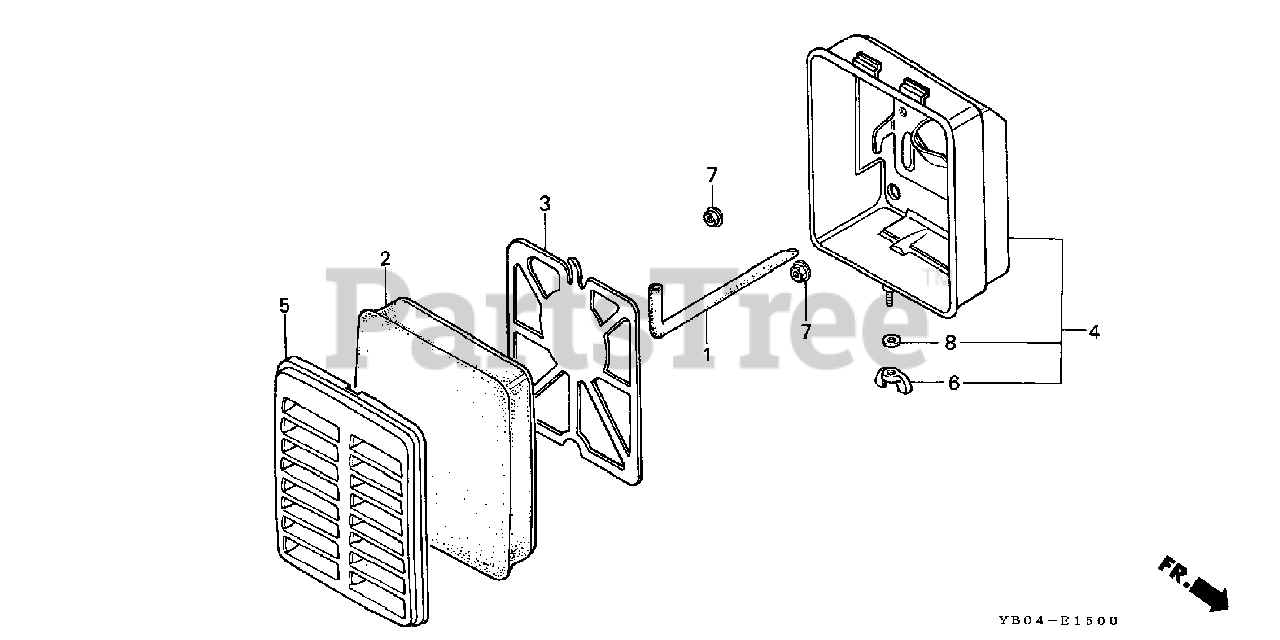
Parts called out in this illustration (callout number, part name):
1	TUBE, BREATHER
2	ELEMENT, AIR CLEANER
3	GRID, AIR CLEANER
4	HOUSING, AIR CLEANER (NOT AVAILABLE)
5	COVER, AIR CLEANER
6	WINGNUT, TOOL BOX SETTING
7	NUT, FLANGE (5MM)
8	WASHER, PLAIN (6MM)
